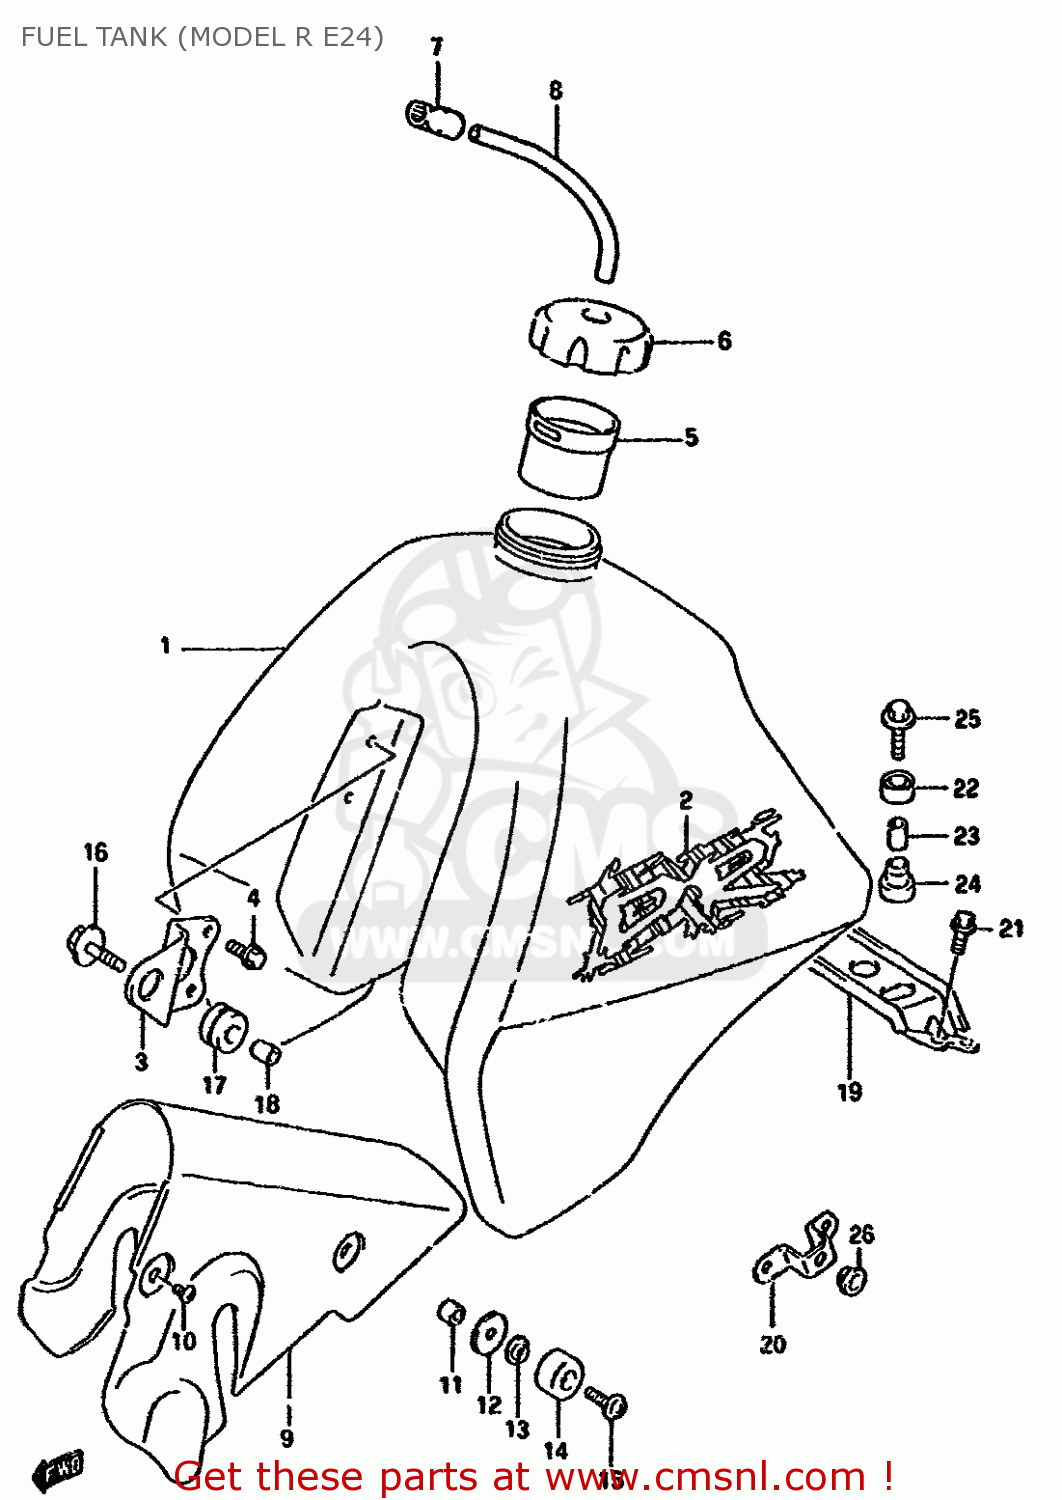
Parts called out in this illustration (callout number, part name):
1	TANK ASSY,FUEL(WHITE)
2	TAPE SET,FUEL TANK
3	BRACKET,FUEL TANK,FRONT
4	BOLT
5	TUBE,FILLER INLET
6	CAP ASSY,FUEL TANK
7	CLAMP,FUEL TANK BREATHER HOSE
8	HOSE
9	HEAT SHIELD,FUEL TANK
10	BOLT
11	SPACER(6.1X14X7.2)
12	WASHER (6.5X26X2.3)
13	WASHER
14	CUSHION
15	SCREW 6X30
16	BOLT(8X25)
17	CUSHION
18	SPACER (8.8X12X12.5)
19	BRACKET,FUEL TANK RR
20	PLATE,FUEL TANK STOPPER
21	BOLT
22	CUSHION
23	SPACER
24	CUSHION
25	BOLT
26	SPACER
27	CUSHION
28	BOLT
29	CUSHION
